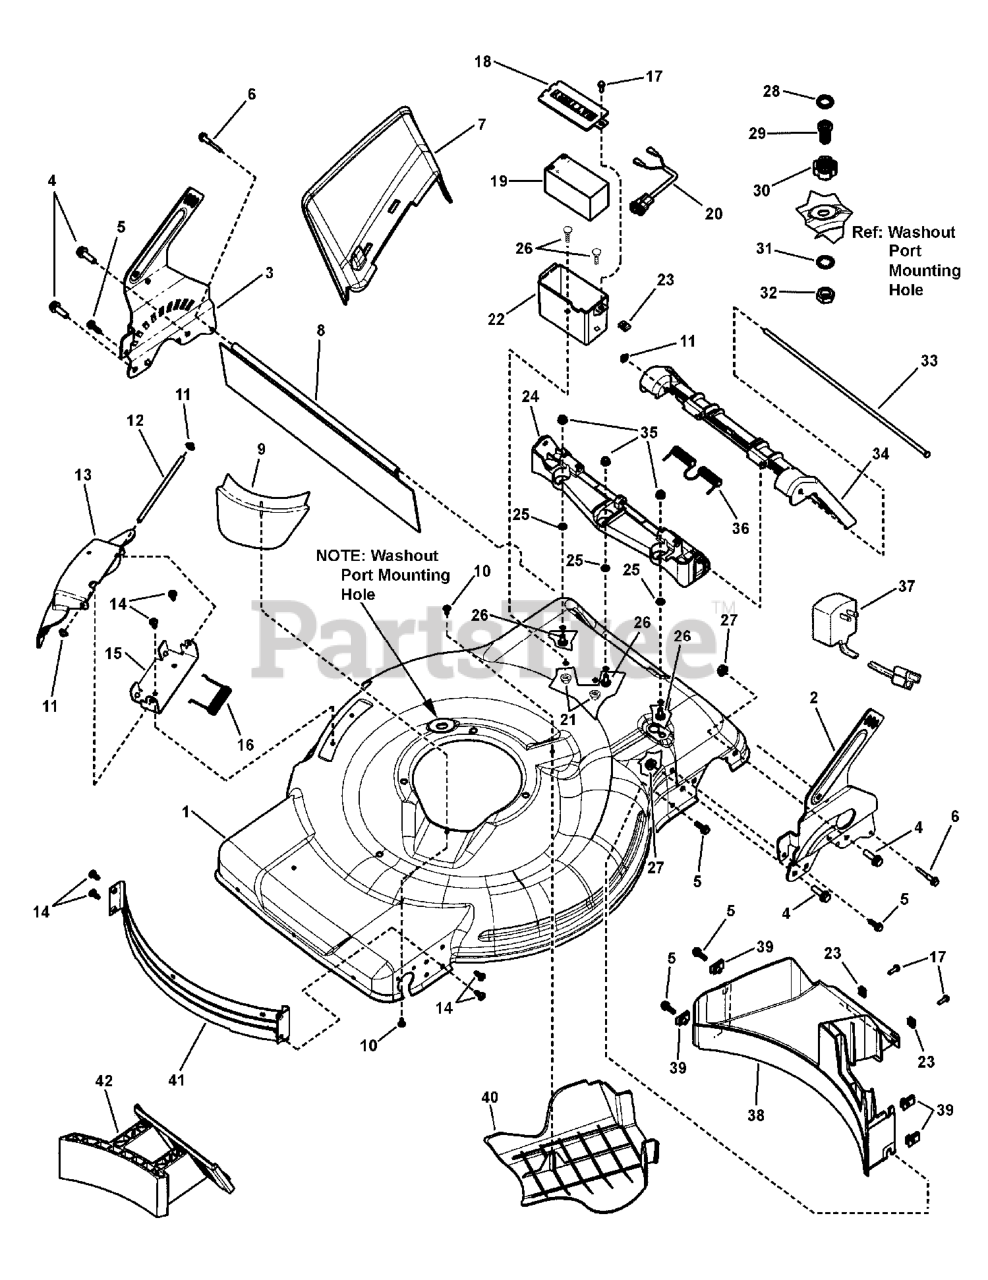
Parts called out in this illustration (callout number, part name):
1	DECK, 22", RWD, ES, Washout
2	BRKT, Rear Wheel, LH, Quick Adjust
3	BRKT, Rear Wheel, RH, Quick Adjust
4	BOLT, 5/16-18 x 1" Hex Flange Lock, GR 5
5	BOLT, 1/4-20 x 3/4" Hex Flange Lock, GR 5
6	BOLT, Drag Shield, 1/4-20 x 1-1/2"
7	CHUTE, Side Discharge, 22" WBM
8	GUARD, Rear 22"
9	FRONT SHIELD, Debris
10	SCREW, 4.8 x 1.59 x 13mm, Round Washer Head Hi-Lo (Torx)
11	PUSHNUT, 1/4"
12	ROD, Pivot
13	COVER, Mulching
14	SCREW, 1/4-20 x .550 Pan Head Torx (T-30)
15	BRACKET, Chute
16	SPRING, Chute (Torsion)
17	SCREW, #10-24 x 5/8" Hex Washer Face Self-Tap, GR 5
18	TOP, Battery Box, Miniature
19	BATTERY, 12V, 1.3 A/HR, Type G Terminals
20	HARNESS, Battery, 1.3 A/HR
21	NUT, 1/4-20 Hex Flange Whiz Lock
22	BOTTOM, Battery Box, Miniature
23	SPEED NUT, #10-24 Retainer w/Extrusion
24	DOOR HINGE, Rear Discharge
25	RETAINER, 1/4" Bolt
26	BOLT, 1/4-20 x 5/8" Flat Head Square Neck, GR 5
27	NUT, 5/16-18 Hex Flange Lock, GR 5
28	WASHER, Hose
29	ADAPTOR, Washout Port, WBM
30	COUPLING, Hose
31	WASHER, 5/8" Internal Tooth Lock
32	NUT, 5/8-11 NC-2B Hex Jam
33	ROD, Pivot, Rear Door
34	DOOR, Rear Discharge
35	NUT, 1/4-20 Hex Flange Lock
36	SPRING, Rear Door (Torsion)
37	CHARGER, Battery, 120V/14V 260MA
38	REAR BAFFLE, Rear Wheel Drive WBM
39	U-NUT, 1/4-20
40	COVER, Belt Drive, Rear
41	BAFFLE, Front
42	PLUG, Mulching, 22" Deck
